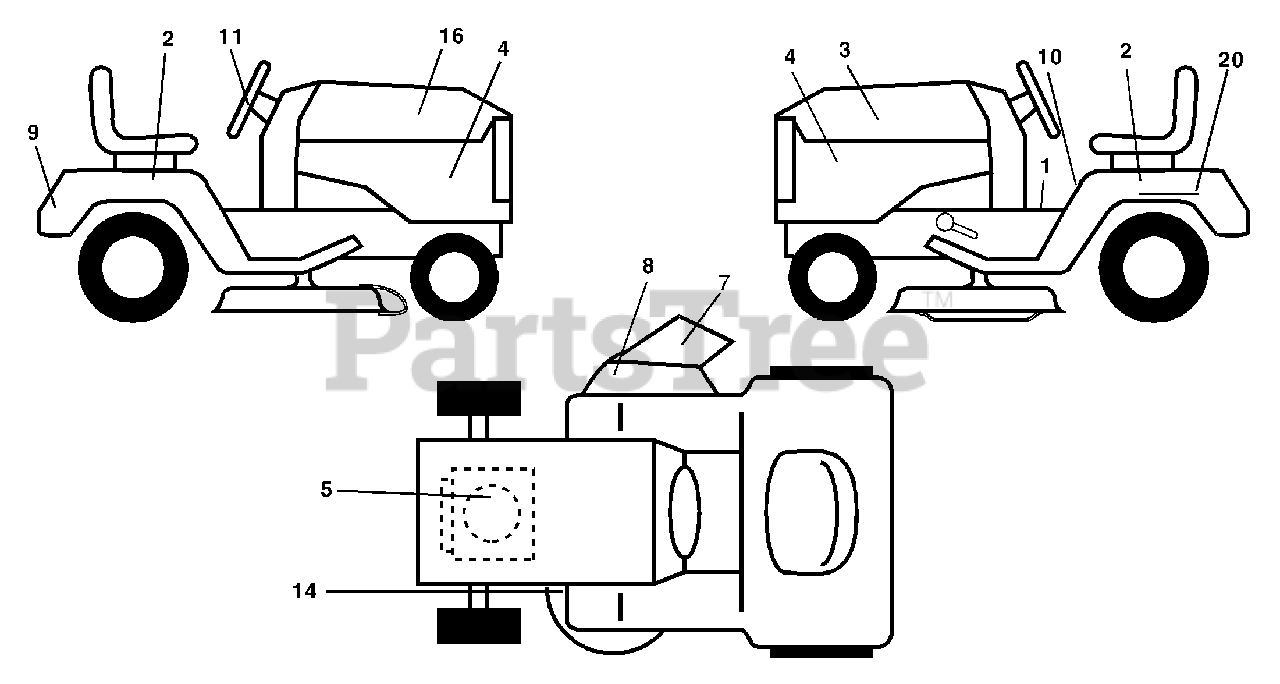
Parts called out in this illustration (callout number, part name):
2	Decal Fender
3	Decal Hood LH
4	Decal Side Panel Logo
5	Decal HP Engine
7	Decal Deck "B" "42"
8	Decal Mower Warn Keep Hand Away
9	Decal Fender Logo
10	Decal Fender Danger E/F
11	Decal Ins Strg Whl
14	Decal V-Belt Schematic
16	Decal Hood Rh
20	Decal Bat Dan/Psn
